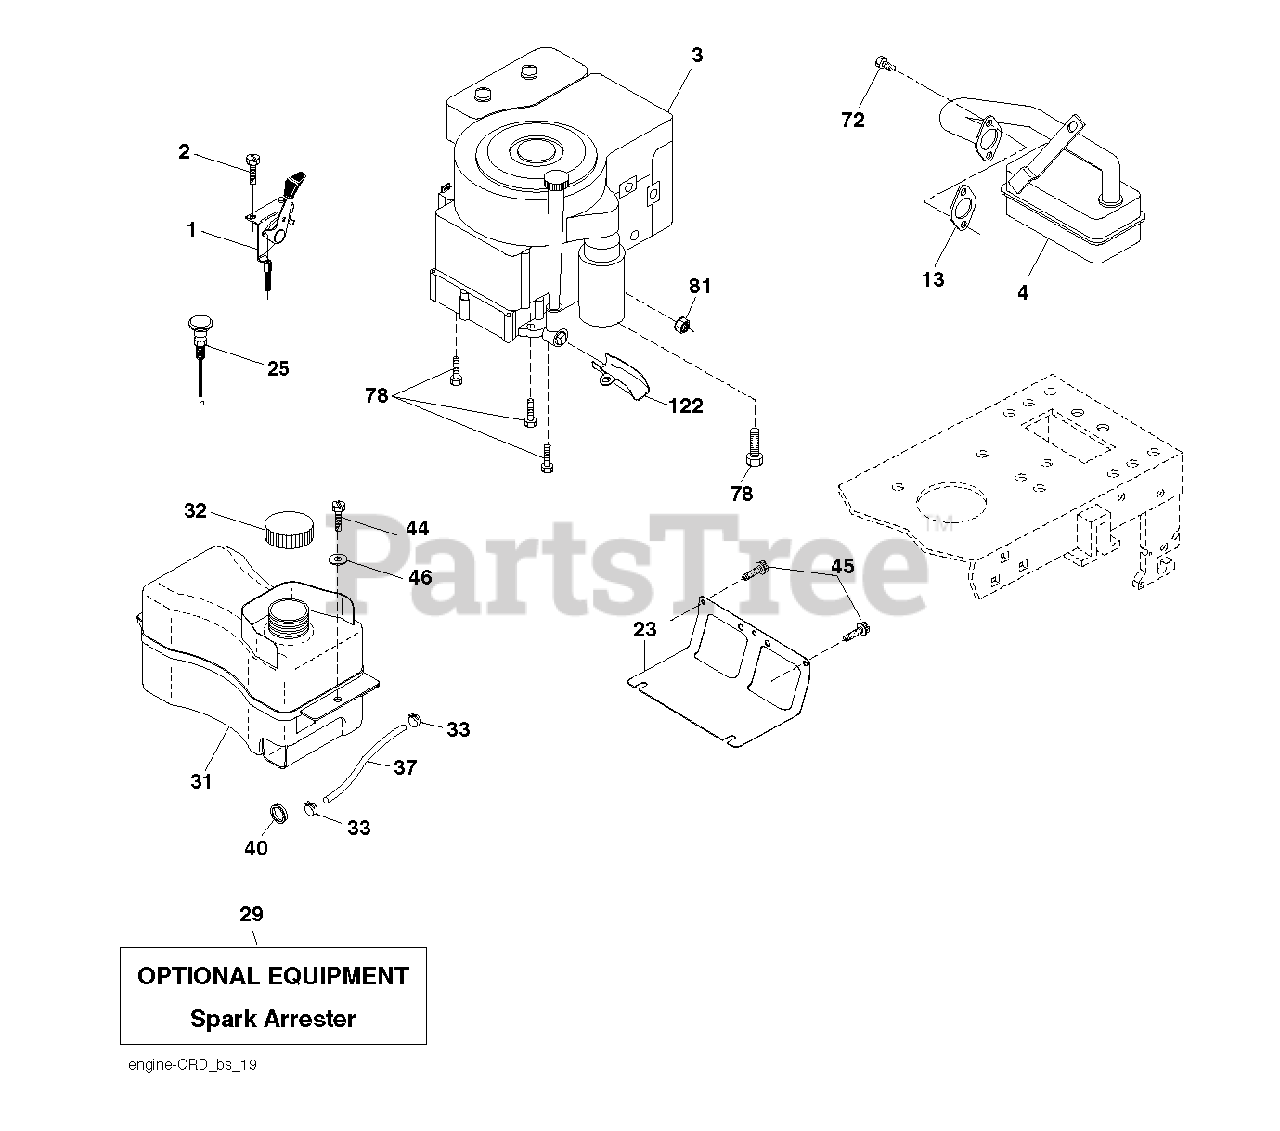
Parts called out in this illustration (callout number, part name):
1	CONTROL.THROTTLE/CHOKE.BLACK
2	SCREW
4	MUFFLER.B&S.MODEL.21.11HP.OHV
23	SHIELD.BROWNING.DBR.GUARD
25	KNOB.ERGO.EXTENDED.RED (1 2)
29	KIT.SPARK ARRESTOR(392390 B&S)
32	CAP ASM.FUEL.2.25"FR.
33	HOSE CLAMP
37	LINE.FUEL.20
40	GROMMET T
44	SCREW HEXWSHR 1/4-20X3/4
45	SCREW, 3/8-16X3/4
72	SCREW.SOCKET HD.5/16-1
78	SCREW.3/8-16
81	NUT
122	EXTENSION DRAIN OIL
